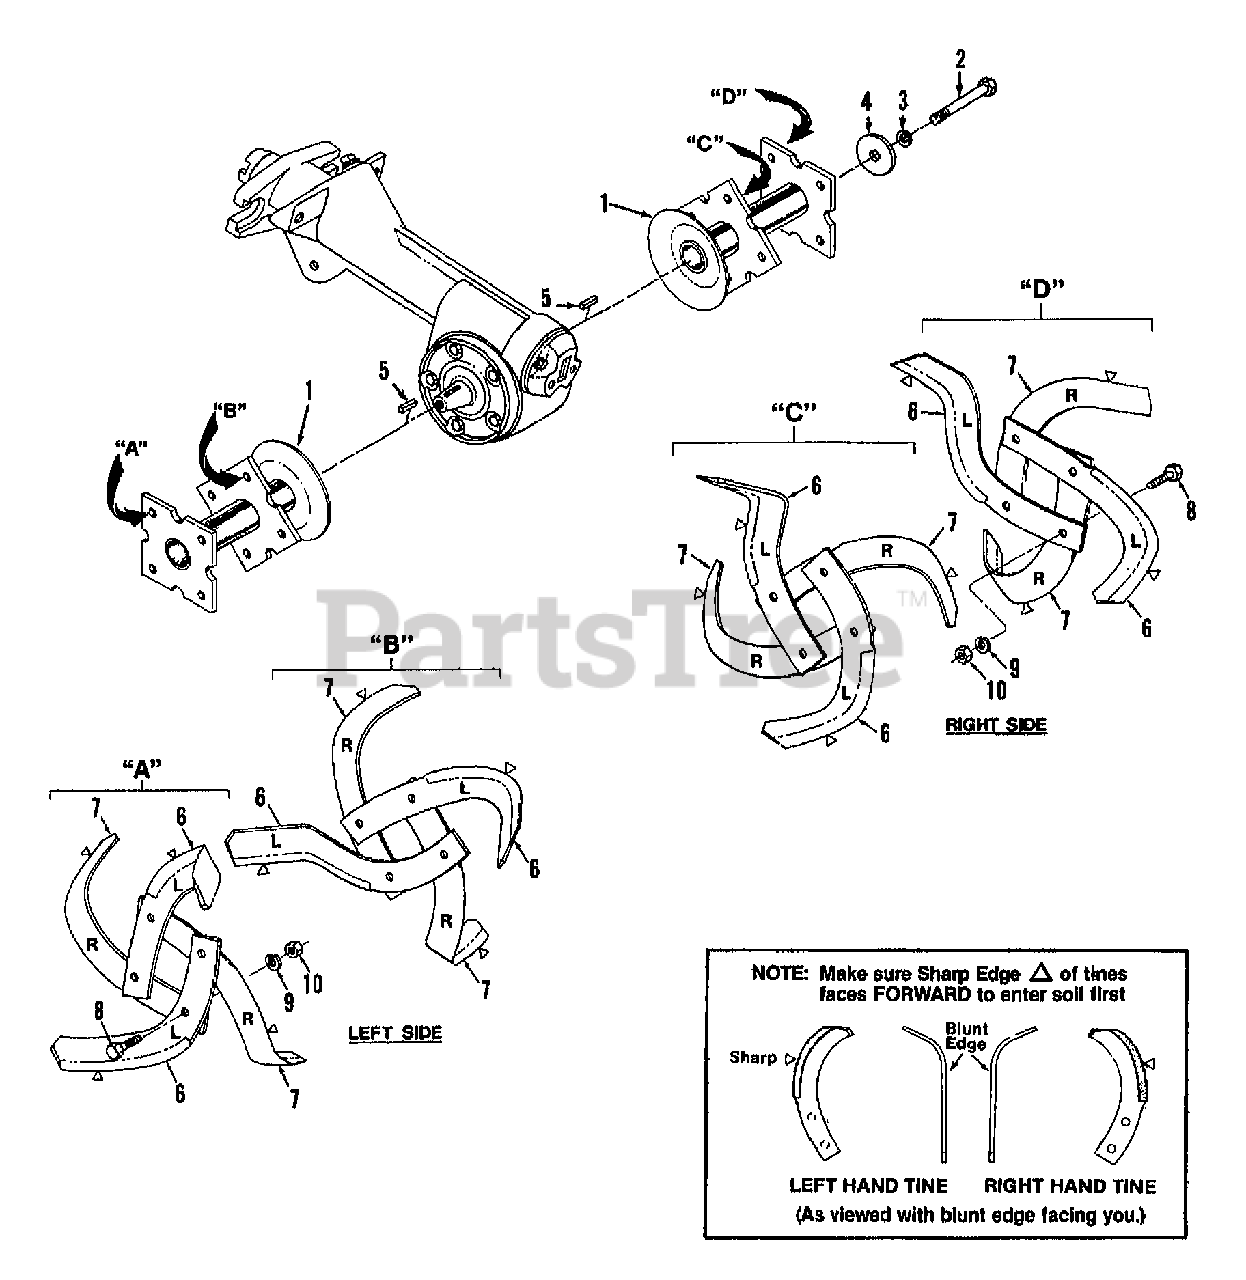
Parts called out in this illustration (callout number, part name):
1	HOLDER-TINE RED
2	SCR-HH 1/2-20X4.75 GR5
3	WASHER-LK .5
4	WASHER-1.5X.531X.187
5	KEY-.188 SQX1.0
6	TINE-BOLO LT W/HDW
7	TINE-BOLO RT W/HDW
8	SCR-HH 3/8-16X1.0 G5 ZP
9	WASHER-LK .375
10	NUT-HEX 3/8-16 ZP
